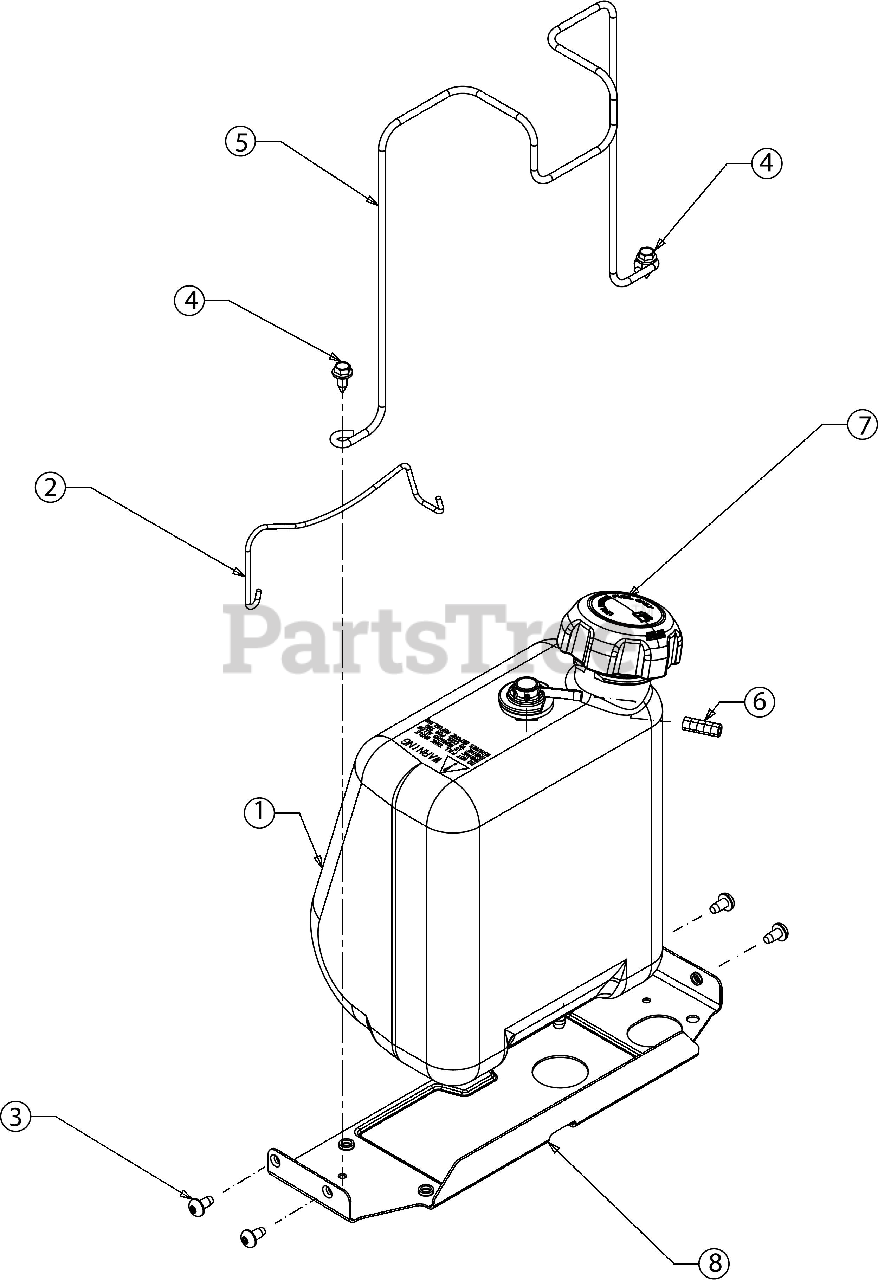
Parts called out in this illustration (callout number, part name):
1	FUEL TANK ASSEMBLY
2	BATTERY ROD ASSEMBLY
3	SCREW 1/4-20 X .5
4	SCREW 1/4-20X.625
5	FUEL TANK SUPPORT ROD
6	VENT HOSE 3/16 ID
7	FUEL CAP W/TETHER
